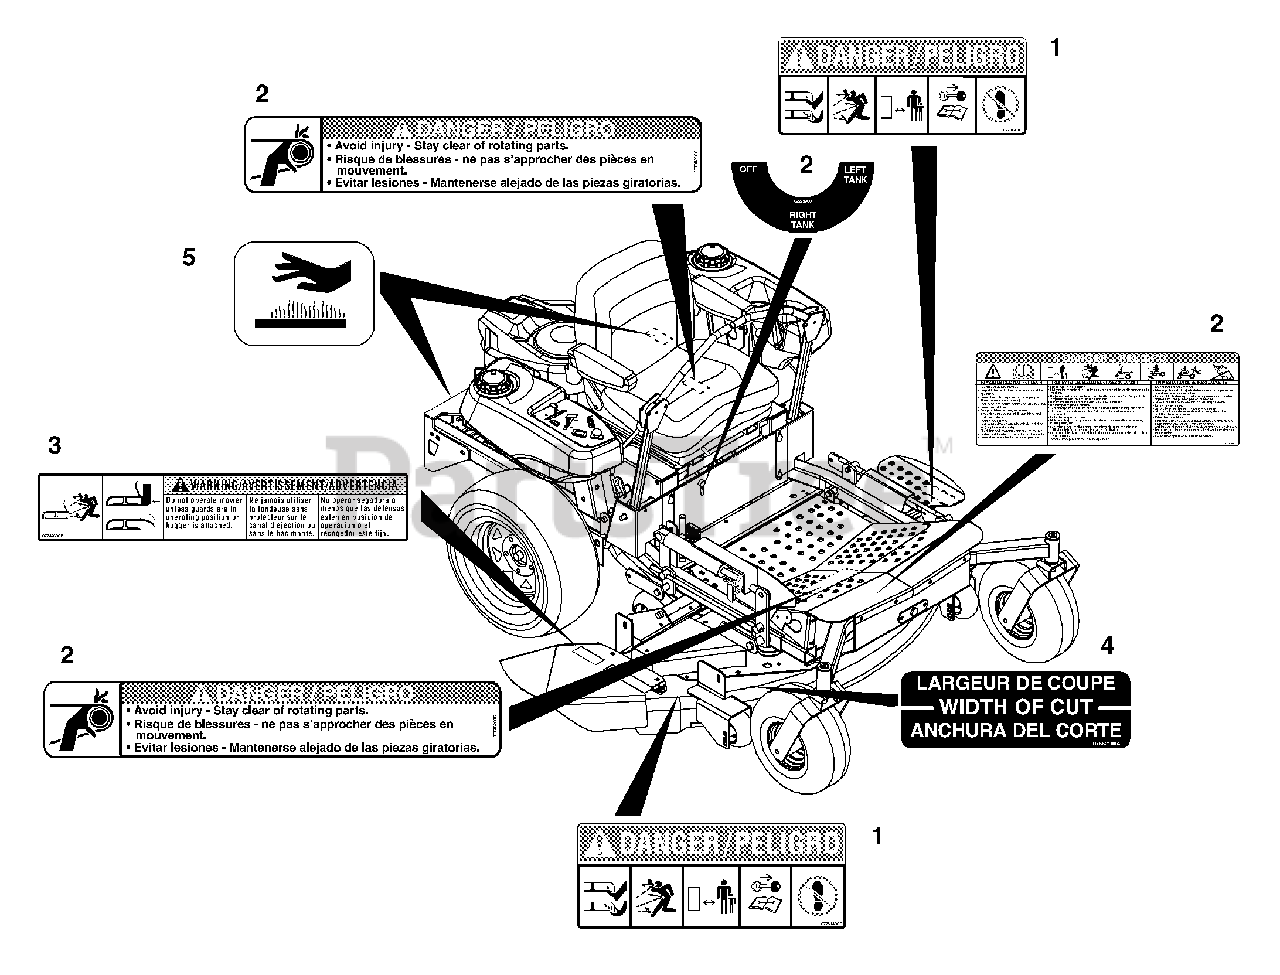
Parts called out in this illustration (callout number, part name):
1	Decal, Mower Pan Head Danger
2	Decal, Set-Common Danger/Fuel
3	Decal, Warning
4	Decal, Width of Cut
5	Decal-Hot Surface
